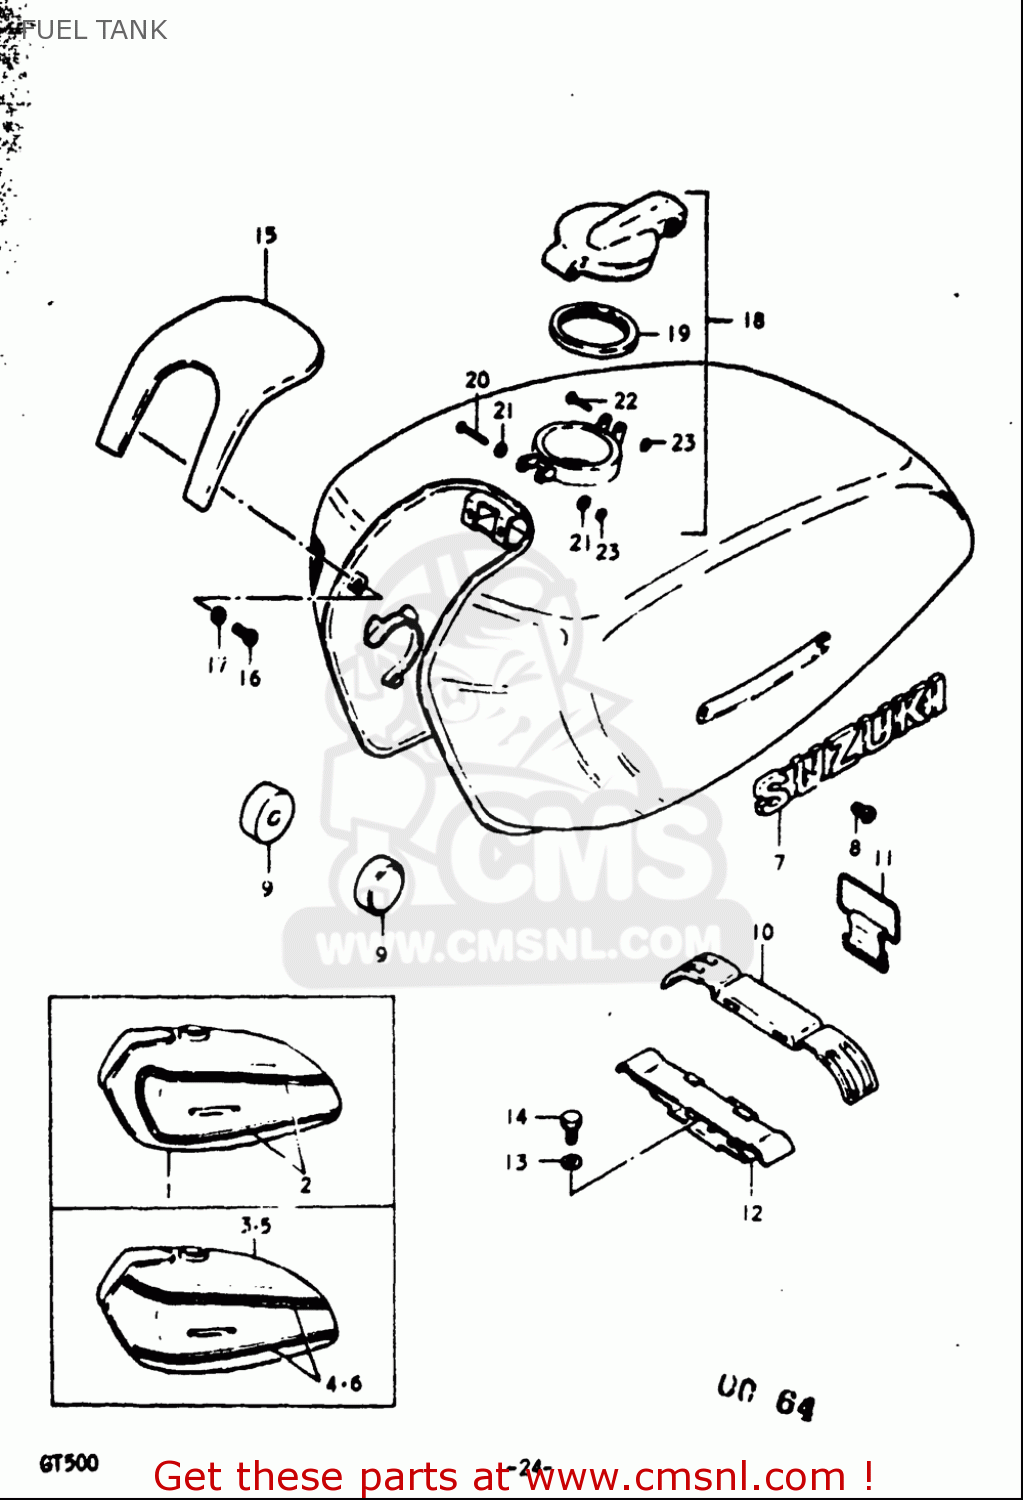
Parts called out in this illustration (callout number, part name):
8	SCREW
9	CUSHION
10	CUSHION
11	BAND
13	WASHER
14	BOLT
16	SCREW
17	WASHER
18	CAP ASSY,FUEL TANK
19	GASKET (NAS)
21	WASHER
23	E RING
